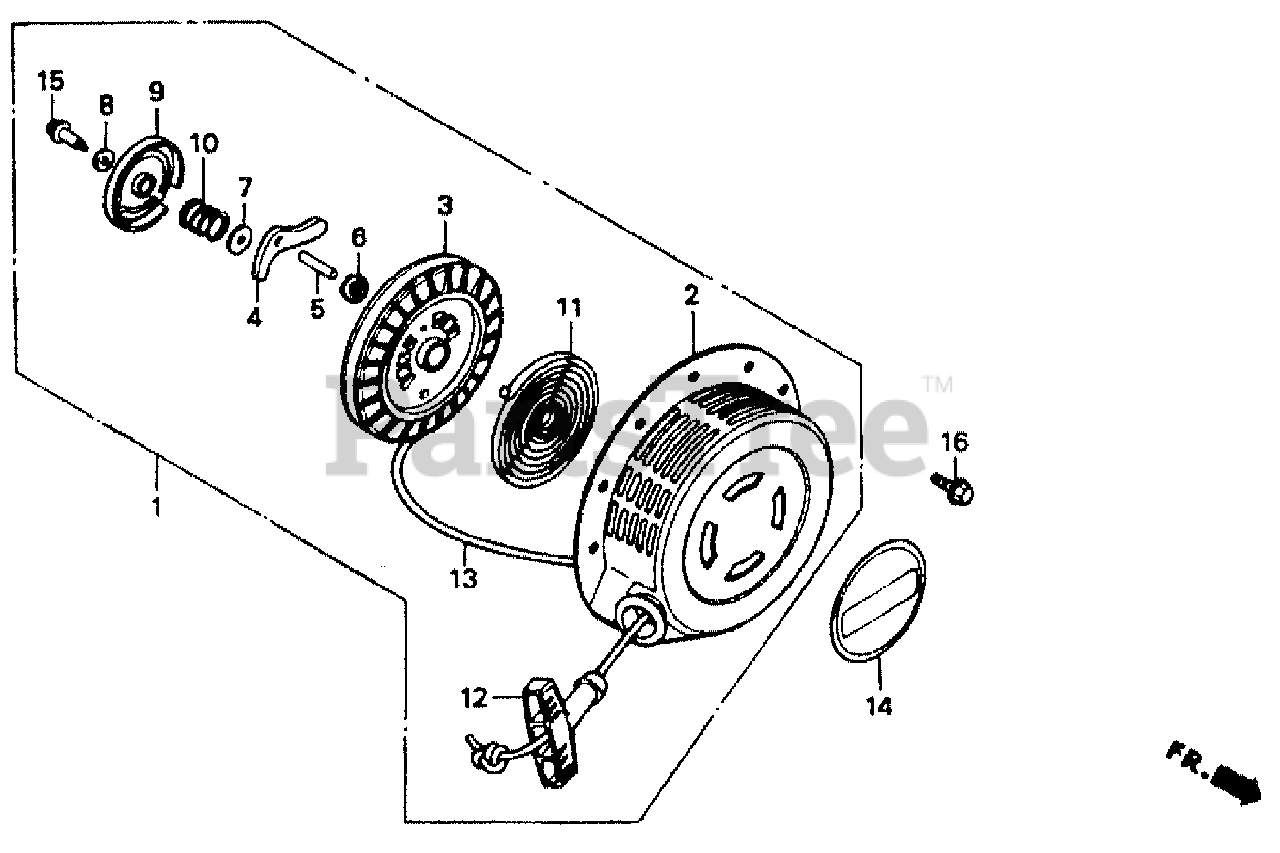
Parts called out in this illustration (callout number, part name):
1	STARTER ASSY., RECOIL *R8* (Honda Code 3419132). (BRIGHT RED)
2	CASE, RECOIL STARTER *R8* (Honda Code 3401619). (BRIGHT RED)
3	REEL, STARTER
4	RATCHET, STARTER
5	SHAFT, RATCHET
6	PLATE, GUIDE
7	PLATE A, FRICTION
8	PLATE B, FRICTION
9	COVER, REEL STARTER
10	SPRING, FRICTION
11	SPRING, RETURN
12	GRIP, STARTER
13	ROPE, STARTER (#5X59") (Honda Code 2026367). (N/A: USE ALT. PNO 08550-ZG921-11)
14	EMBLEM (EXTERNAL-ALERT)
15	BOLT, REEL COVER
16	BOLT, FLANGE (6X8)
